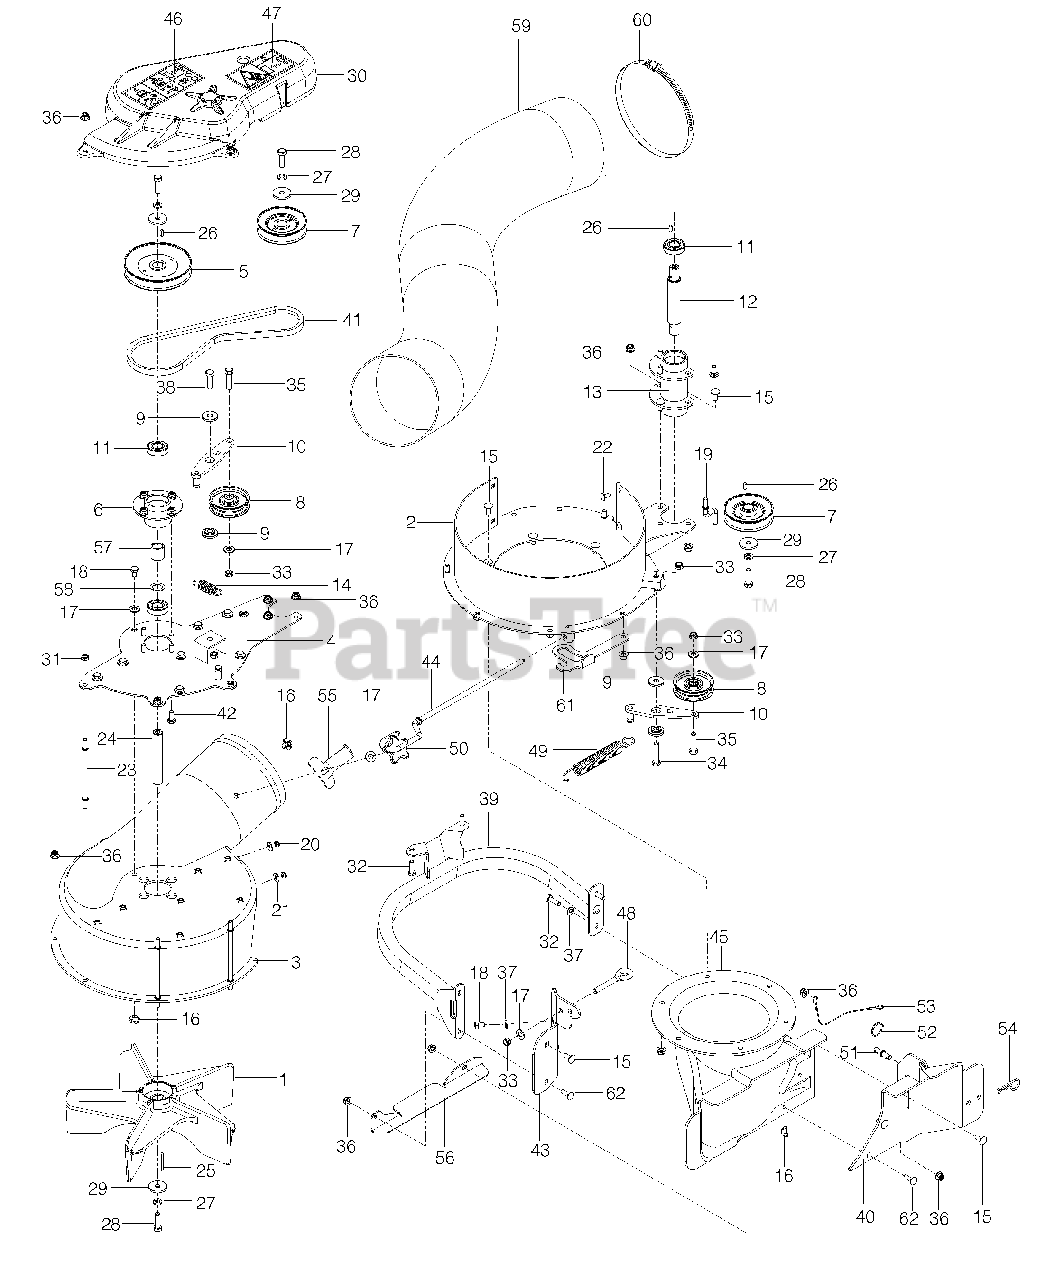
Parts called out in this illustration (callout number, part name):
2	Blower Ring
3	Housing, Impeller
7	Pulley, Drive
9	Bushing, Brake
10	Arm, Idler
12	Shaft, Spindle
13	Tube, Spindle
14	Spring, Idler
15	Rhsnb 5/16-18 X3/4
16	Nut 5/16-18 Tee
17	Washer 3/8 Sae Flt
18	Hcs 5/16-18 X 1/2
19	Keeper, Belt
20	Nut 1/4-20 Hex Thin Nyloc
21	Washer 1/4 Flat
22	Rhssnb 1/4-20 X 5/8
23	Pin, Retention
24	Shaft, Impeller
25	Key 3/16 X 11/2 Sq
26	Key 3/16 X 1/2
27	Washer, 3/ Splt Lock
28	Bolt 3/8-24 X 11/4 Hex Gr 8
29	Washer, Hardened
30	Shield W/ Decals, Belt
31	Nut 5/16-18 Hex Jam
32	Hcs 5/16-18 X 1
33	Nut, 3/8-16 Hex Jam Nyloc
34	Hcs 3/8-16 X 13/4
35	Hcs 3/8-16 X 11/2
36	Nut 5/16-18 Hex Flg Nyloc
37	Washer 5/16 Sae Flat
38	Hcs 3/8-16 X 11/4
40	Mount, Rear, 60"
42	Hcs 5/16-18 X3/4
43	Bracket, Mount, Ft
44	Pin, Mount
45	Housing, Blower
46	Decal, Warning
47	Decal, Severing
49	Spring, Deck Drive
50	Knob 5/16-18 X 1/2
51	Pin, Mount
52	Retainer, Ring
54	Hairpin #4
55	Bracket, Retainer
56	Bracket, Diverter Blk
60	Clamp, Hose
62	Rhsnb 5/16-18 X 1
